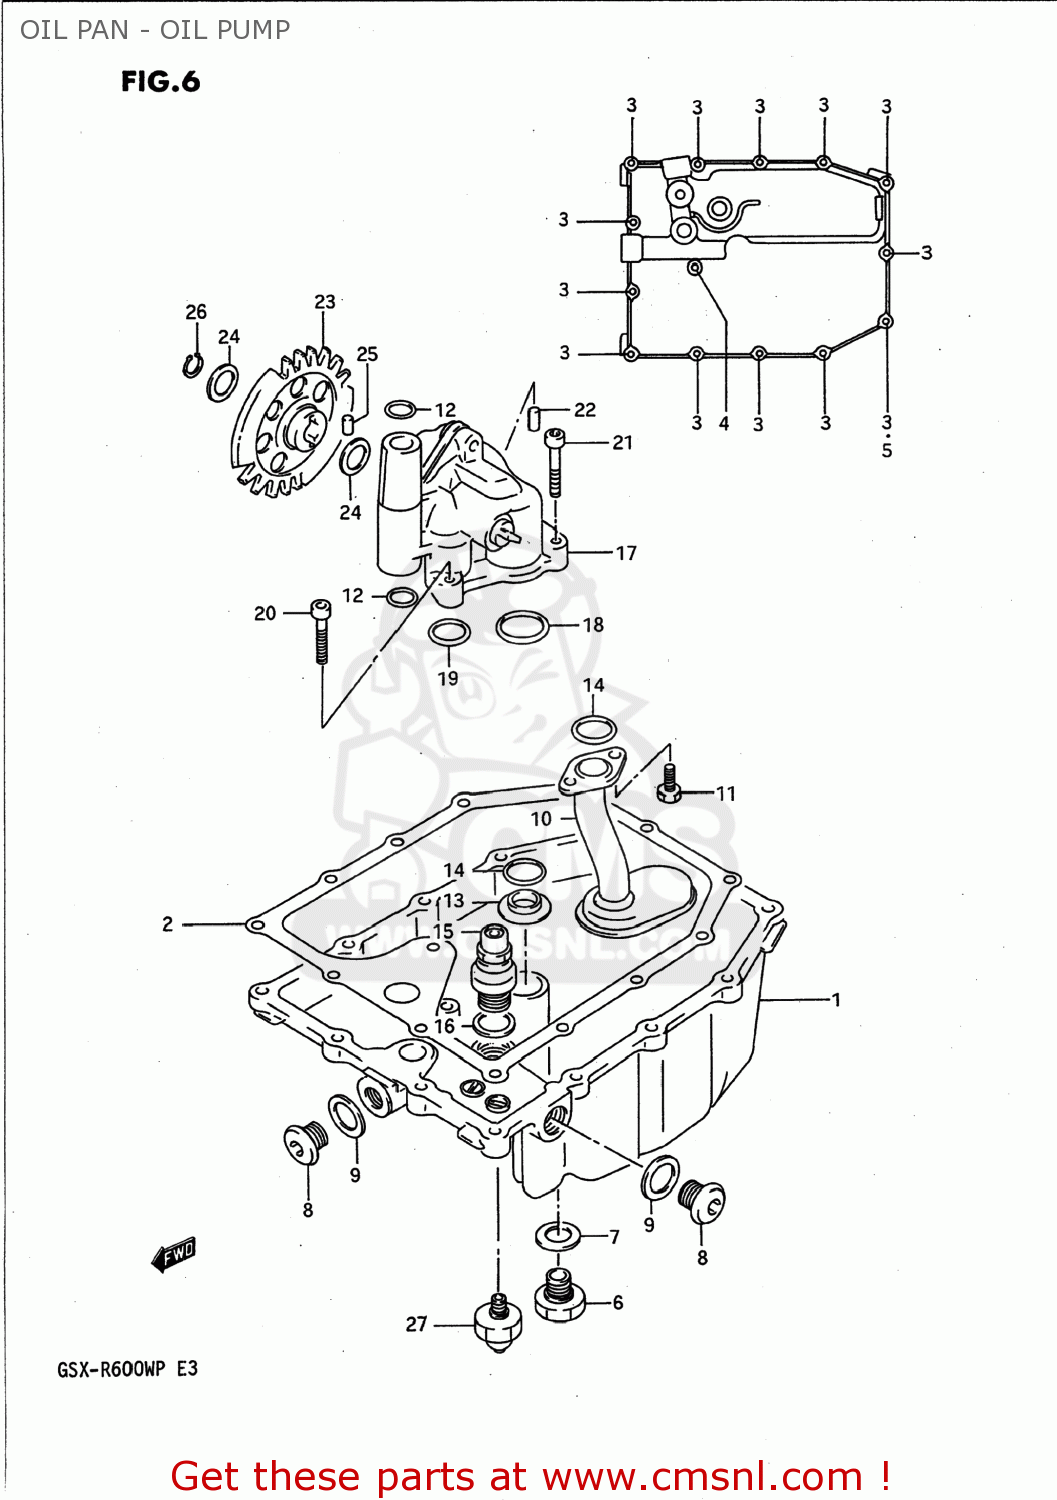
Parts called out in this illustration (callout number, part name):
1	PAN,OIL
2	GASKET,OIL PAN
3	BOLT
4	BOLT
5	GASKET(5.8X11X1.2) (NAS)
6	PLUG
7	GASKET(14X19.2X2) (NAS)
8	PLUG
9	GASKET(16X22X2) (NAS)
10	STRAINER COMP,ENGINE OIL
11	SCREW
12	O RING(D:2.4,ID:11.8)
13	GASKET,OIL OUTLET (NAS)
14	O RING(D:3.2,ID:17.8)
15	VALVE ASSEMBLY,OIL RELIEF
16	GASKET(16X22X2) (NAS)
17	PUMP ASSY,ENGINE OIL
18	O RING(D:2.4,ID:26.2)
19	O RING(D:3.2,ID:17.8)
20	BOLT
21	BOLT
22	PIN
23	GEAR,OIL PUMP DRIVEN(NT:37)
24	SHIM
25	PIN(5X18)
26	CIRCLIP,12 MM
27	SWITCH ASSEMBLY,OIL PRESSURE
